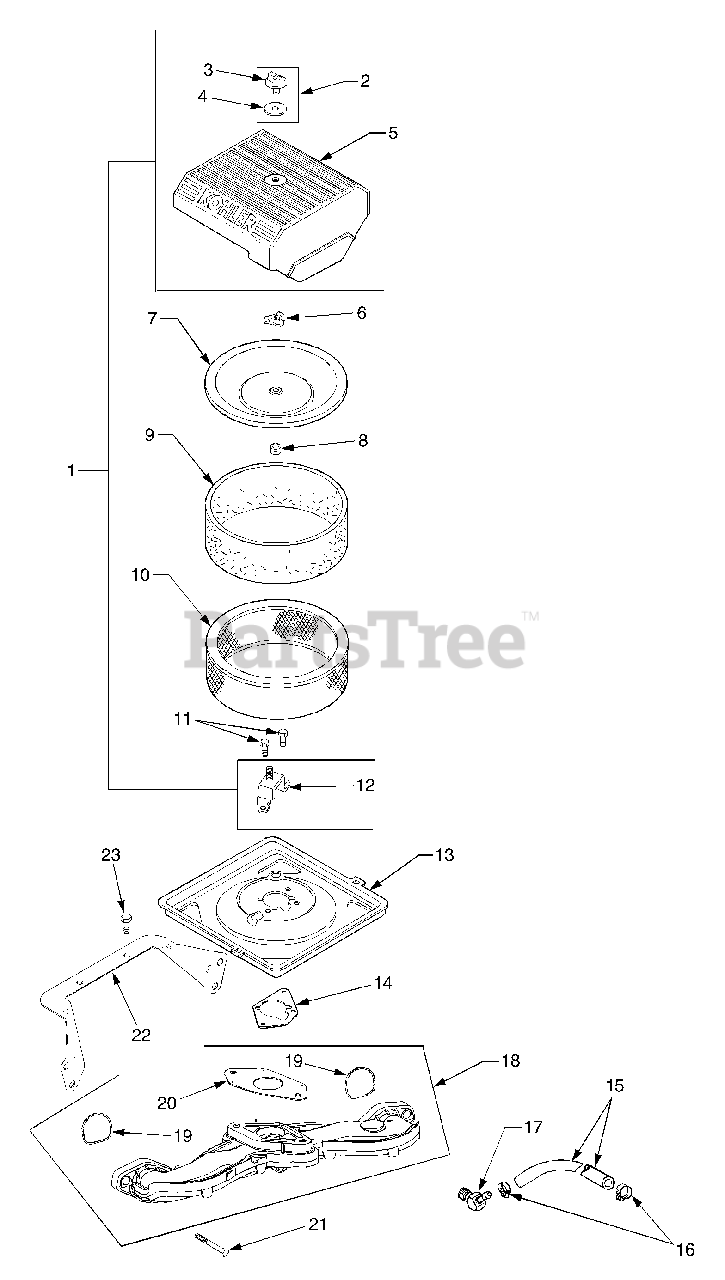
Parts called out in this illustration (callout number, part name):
1	Kit, Air Cleaner Cover
2	Kit, Knob w/Seal
4	Seal, Air Cleaner Cover Knob
5	Cover, Air Cleaner
7	Cover, Inner Air Cleaner
8	Seal, Inner Air Cleaner
9	Precleaner, Element
10	Element, Air Cleaner
11	Screw, Hex Flange, M6 x 1.0 x 16
12	Bracket, Air Cleaner Base
13	Base, Air Cleaner
14	Gasket, Air Cleaner Base
15	Line, Fuel 17"
16	Clamp, Hose
17	Connector, Hose 45°.
18	Manifold, Intake
19	O-Ring, Intake Manifold
20	Gasket, Carburetor
21	Screw, Hex Flange, M6 x 1.0 x 40
22	Bracket, Air Cleaner Base
23	Screw, Hex Flng, M5 x 0.8 x 10
